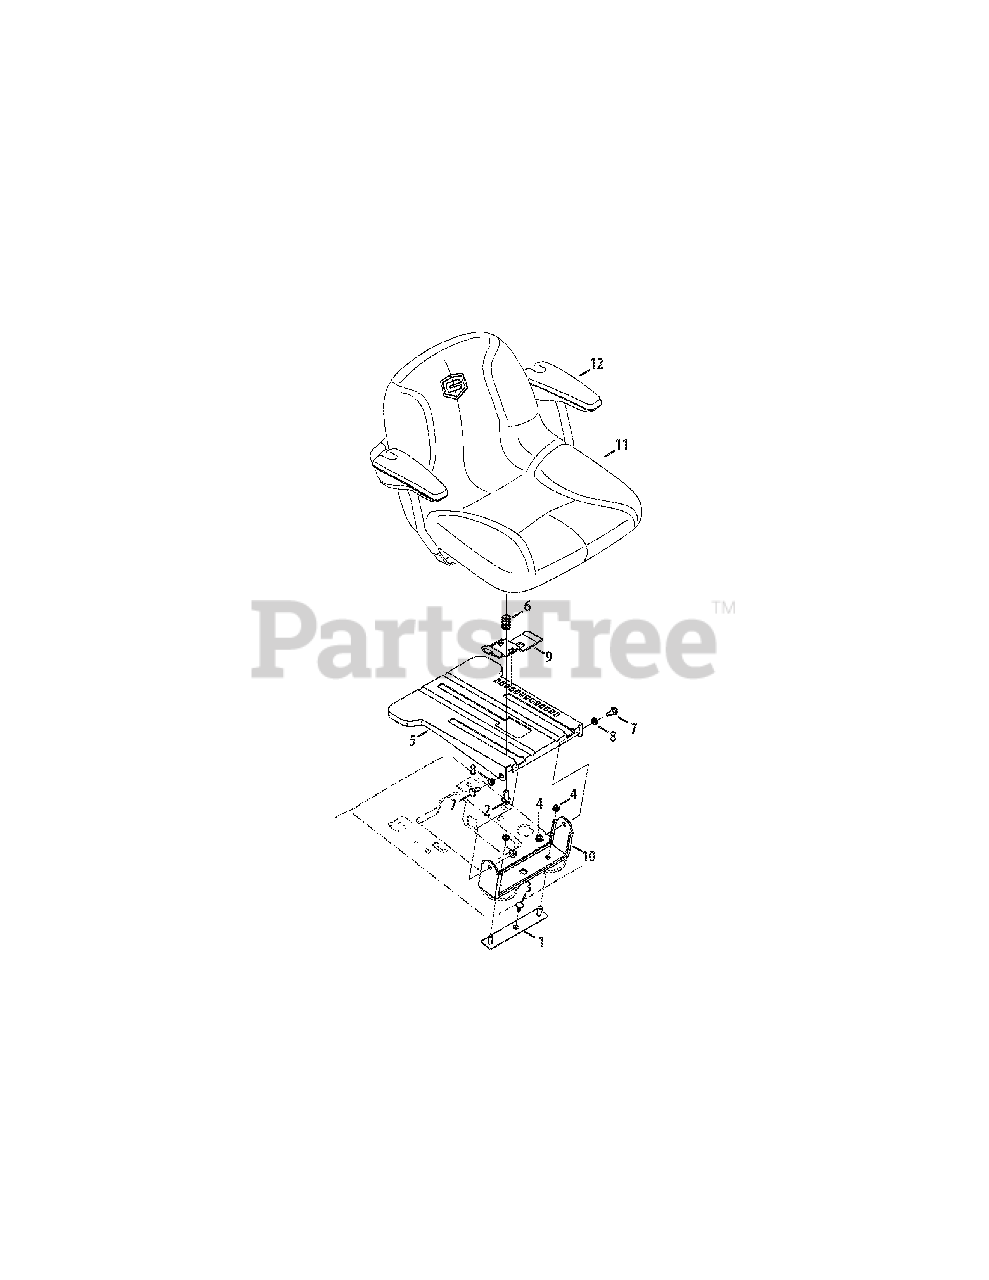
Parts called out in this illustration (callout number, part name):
1	Seat Pivot Plate Assembly
2	Hex Flange Screw, 3/8/16, .875, Gr5
3	Ratchet Clip
4	Nut, Flange Lock, 5/16-18, Grf
5	Bracket, Mounting, Seat
6	Compression Spring, .68 x 1.065 x .055
7	Shoulder Screw, .435 x .178, 5/16 x .56
8	Flange Bearing, .4385 ID
9	Seat Lever
10	Pivot Bracket, Tall
11	Seat
12	Arm Rest Kit
